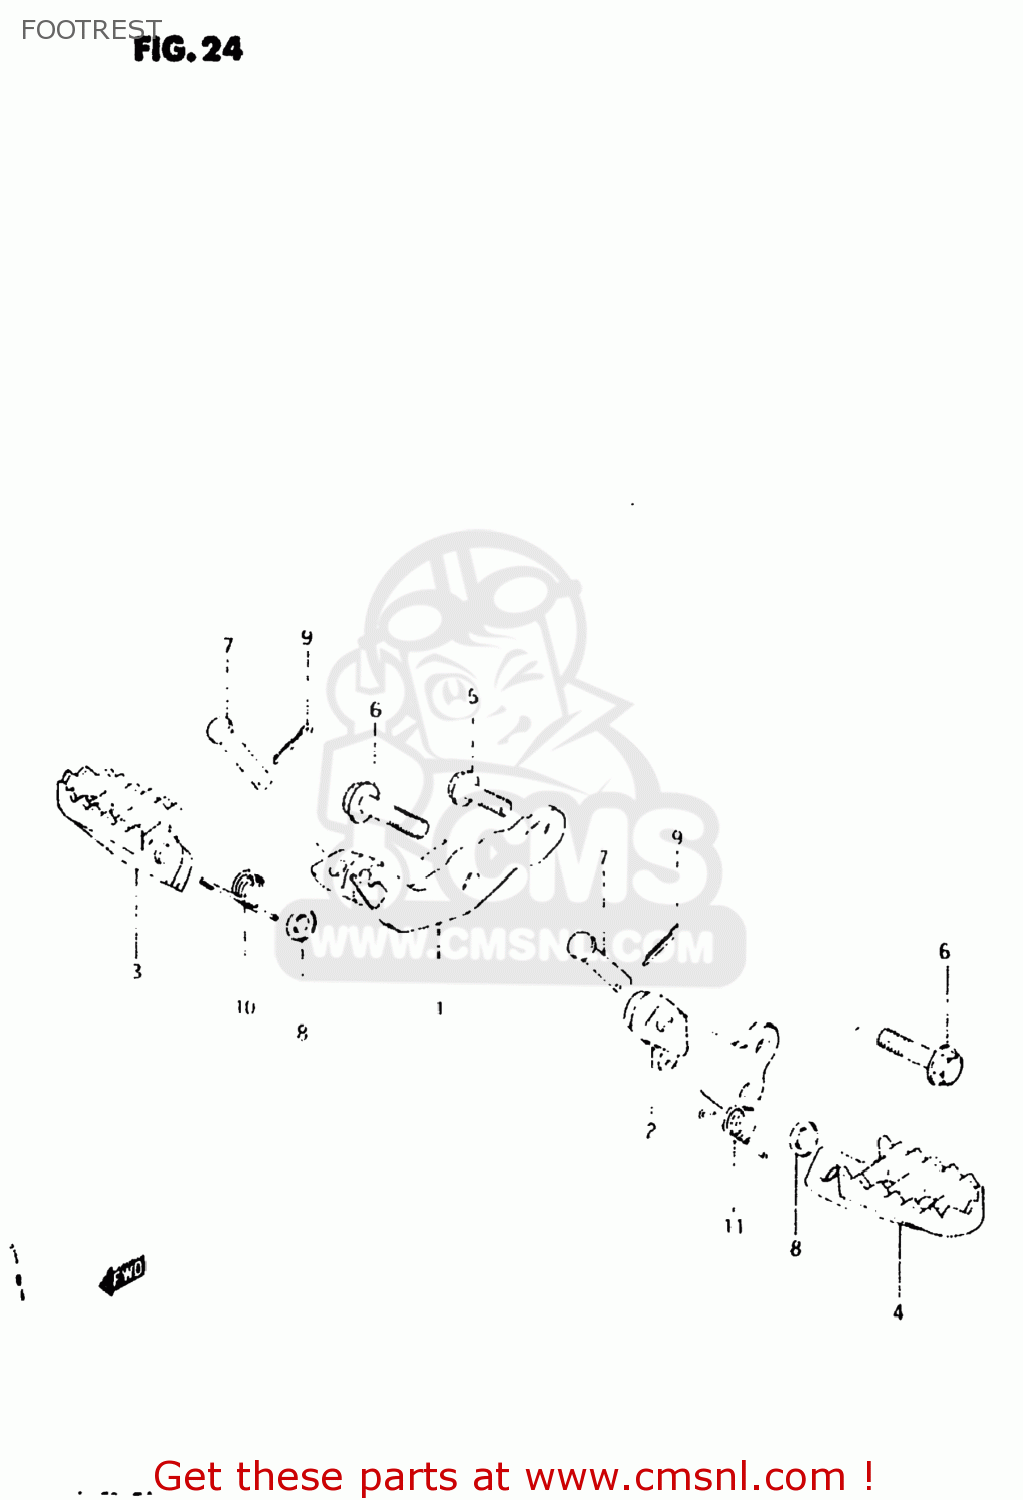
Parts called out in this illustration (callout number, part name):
1	BAR,FRONT FOOTREST
2	BAR,FRONT FOOTREST,LEFT
3	FOOTREST,RIGHT
4	FOOTREST
5	BOLT
6	BOLT
7	PIN
8	WASHER
9	PIN 20X20
10	SPRING
11	SPRING,FOOTREST,LEFT
